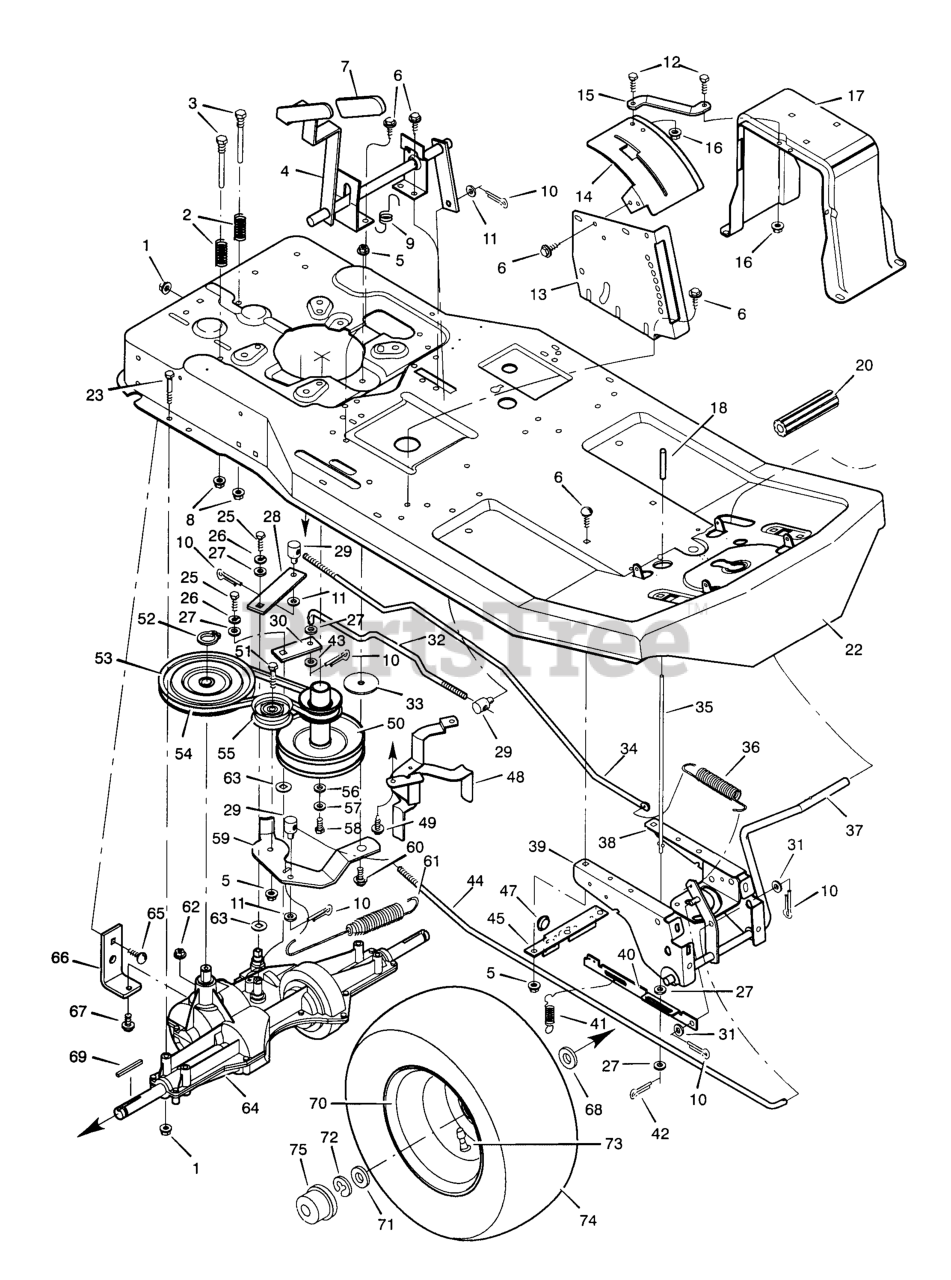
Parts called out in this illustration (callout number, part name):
1	Locknut, Flange
2	Spring, Compression
3	Guide, Belt
4	Shifter Assembly
5	Locknut, Flange
7	Grip, Shift Lever
8	Hex Nut
9	Spring, Extension
10	Pin, Cotter
11	Washer
12	Bolt, Hex
13	Plate, Index
14	Gate, Shift
15	Brace, Shift Gate
16	Locknut, Flange
17	Support, Seat
18	Grip, Parking Brake
20	Pedal, Rubber
22	Frame Assembly
23	Bolt, Hex
25	Bolt, Hex
26	Lockwasher
27	Washer
28	Yoke, Brake
29	Nut, Adjusting
30	Yoke, Shift
31	Washer
32	Rod, Shift
33	Washer, Hardened
34	Rod, Brake
35	Rod, Parking Brake
36	Spring, Extension
37	Lever, Pedal
38	Plate, Left Suspension
39	Plate, Right Suspension
40	Link, Parking Brake
41	Spring, Extension
42	Pin, Cotter
43	Washer
44	Rod, Clutch
45	Stop, Parking Brake
47	Grommet
48	Guide, Belt
50	Pulley Assembly, Stack
51	Bolt, Hex
52	Ring, Retainer
53	Pulley, Drive
54	Belt, Motion Drive
55	Pulley, Idler
57	Lockwasher
58	Bolt, Hex
59	Bracket, Idler
60	Bolt, Shoulder
61	Spring, Extension
62	Locknut, Hex
64	Transaxle, Dana Model 4450-1 **
65	Bolt, Carriage
66	Bracket, Transaxle
67	Bolt, Hex
69	Key, Square
70	Wheel & Tire Assembly
72	E- Ring
73	Valve Stem
74	Tire *
75	Hub Cap
